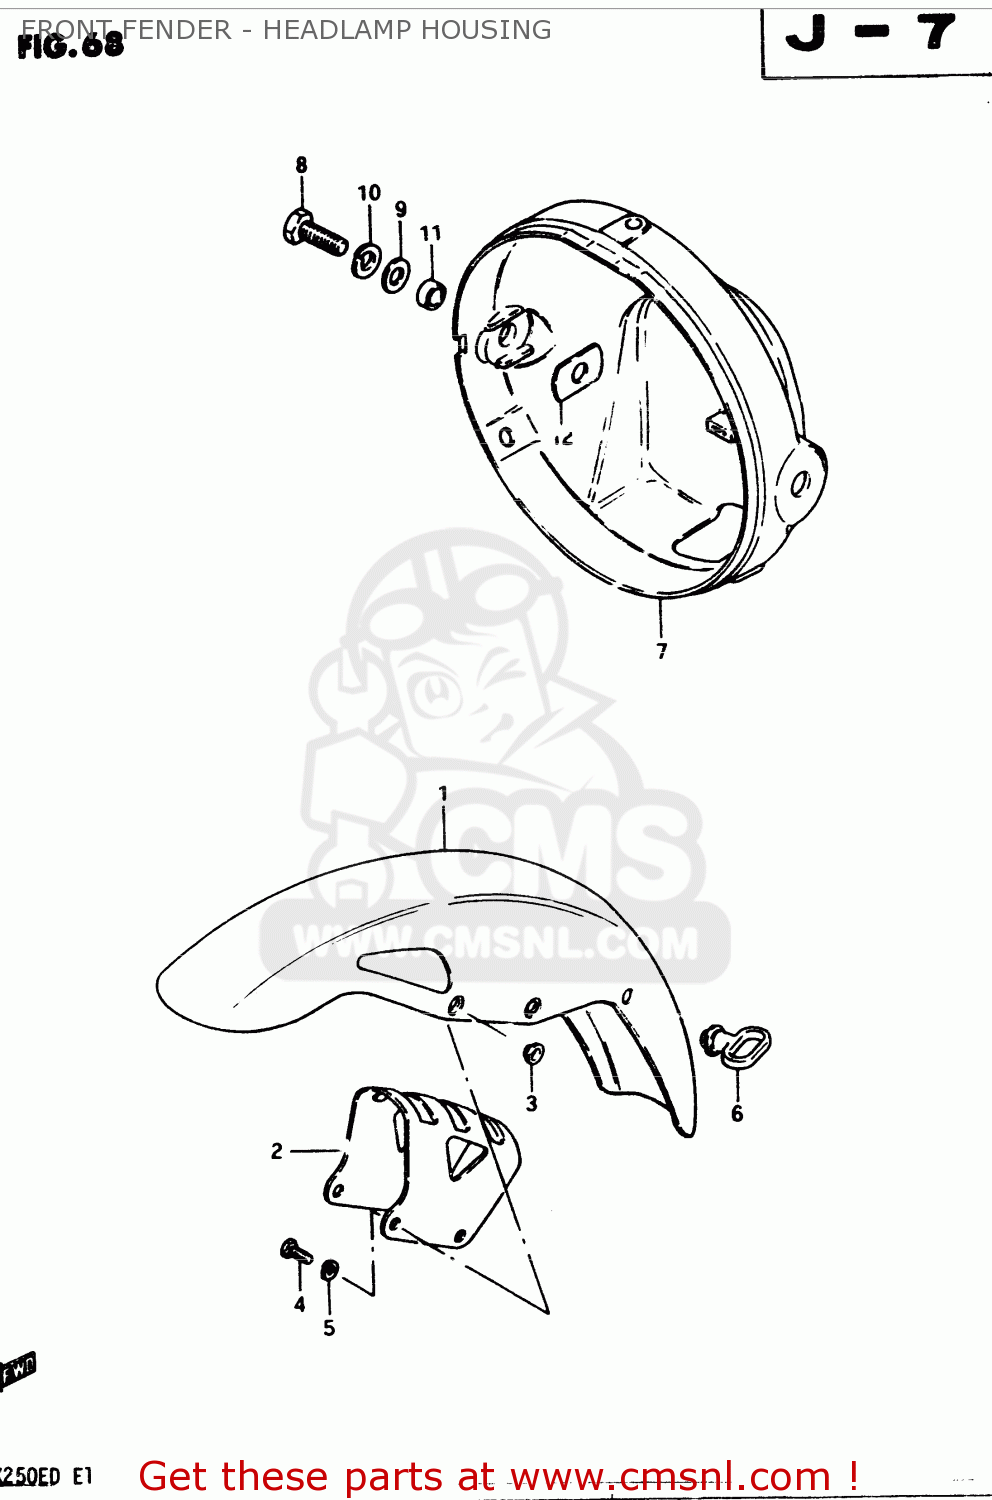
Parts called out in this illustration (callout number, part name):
1	FENDER,FR
2	BRACE,FRONT FENDER
3	WASHER
4	BOLT
5	LOCK WASHER
6	GUIDE,CABLE
7	HOUSING,HEADLAMP
8	BOLT
9	WASHER
10	LOCK WASHER
11	SPACER (8.8X12X7)
12	CUSHION
